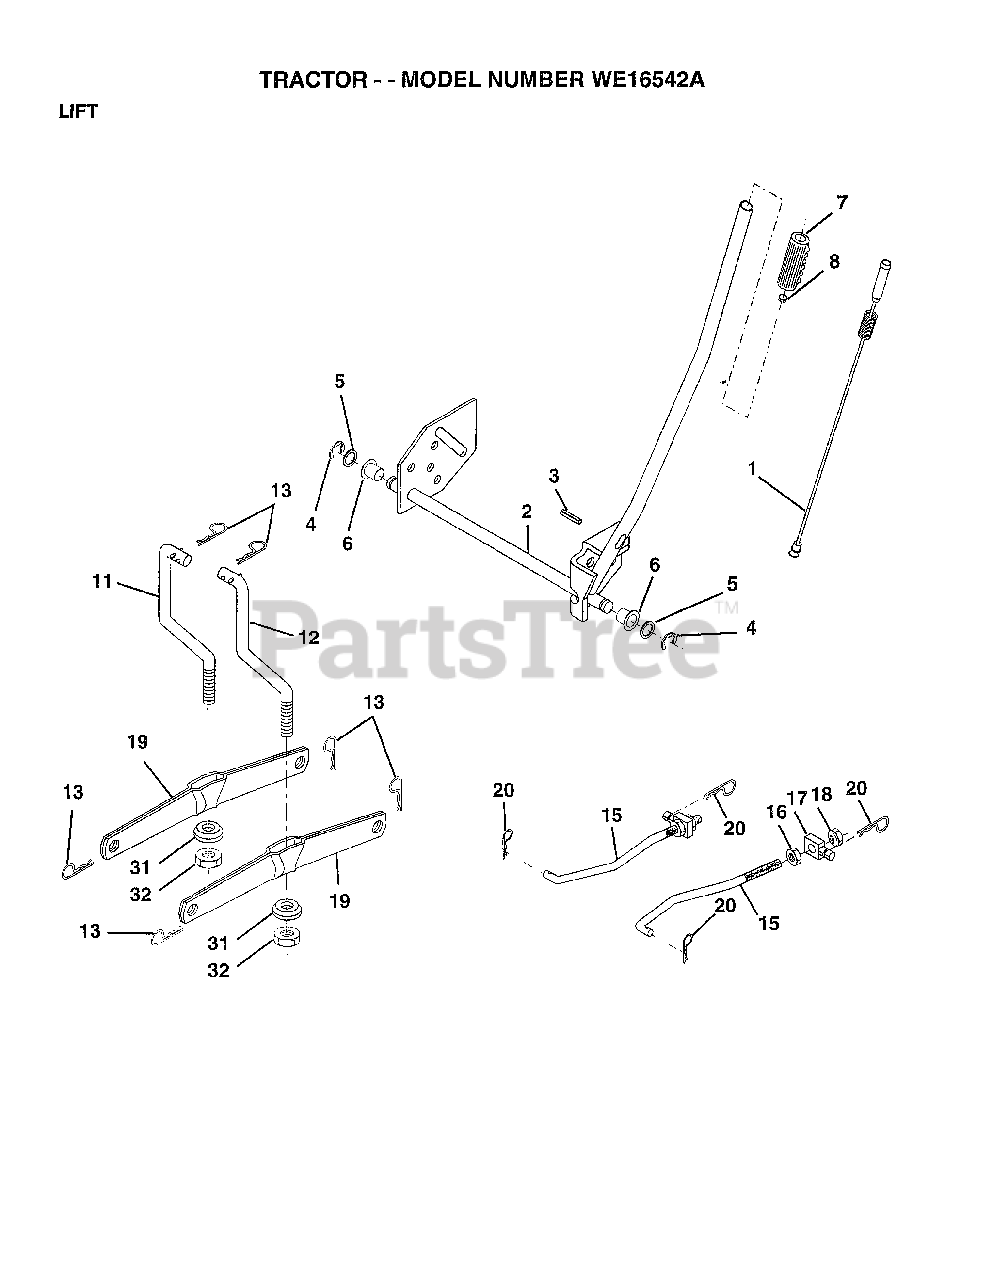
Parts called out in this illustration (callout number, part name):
1	WIRE ASM W.SPRING
2	"SHAFT ASM LIFT,RH"
3	PIN-GROOVE LT
5	WASHER
6	NYLON BEARING
7	GRIP
15	LINK.FRONT
16	NUT
17	TRUNION
18	NUT.LK.W/WSH.1/2.
19	ARM SUSP REAR
20	RETAINER.SPRING
31	BEARING PVT LH
32	NUT.CROWNLOCK.3/8
